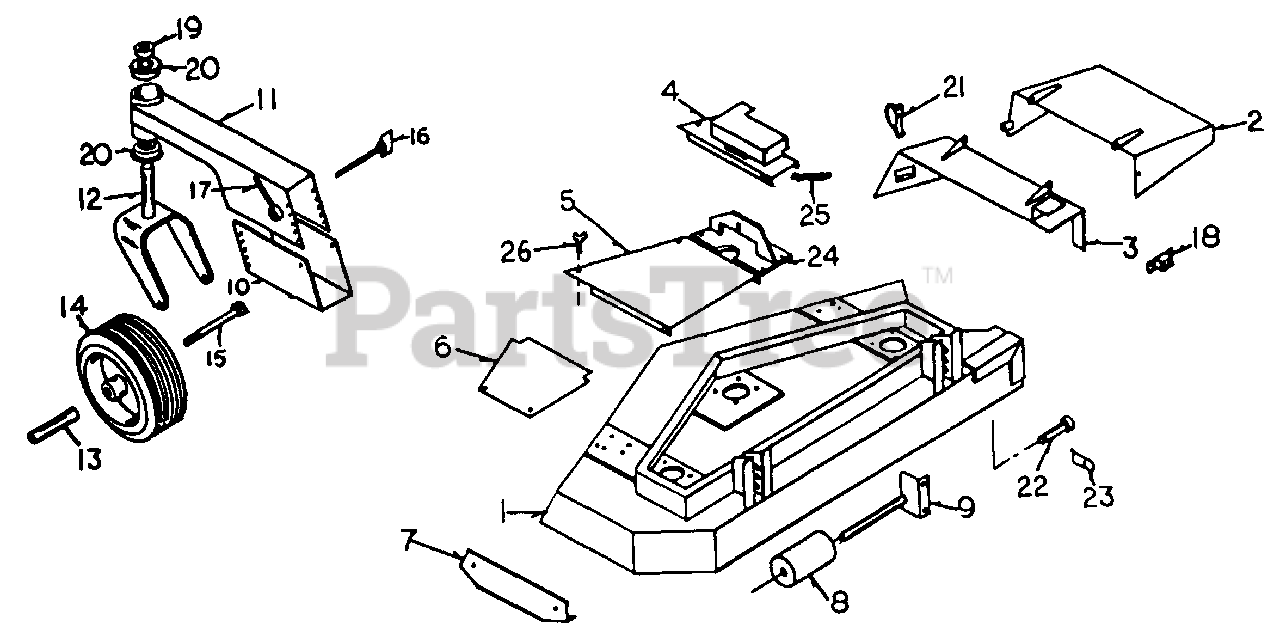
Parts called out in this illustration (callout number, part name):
1	Deck, 42"
3	Foot Guard Mount
8	Anti-scalp Roller
9	Shaft & Bracket
10	Gauge Wheel Mount Bracket
11	Gauge Wheel Mount
12	Fork
13	Axle
14	Gauge Wheel Assembly
15	Axle Bolt
18	10 Amp Circuit Breaker
19	Set Collar, 1"
23	Hair Pin Cotter
24	Deck Mount
26	Thumb Screw, 1/4-20 x 1/2"
